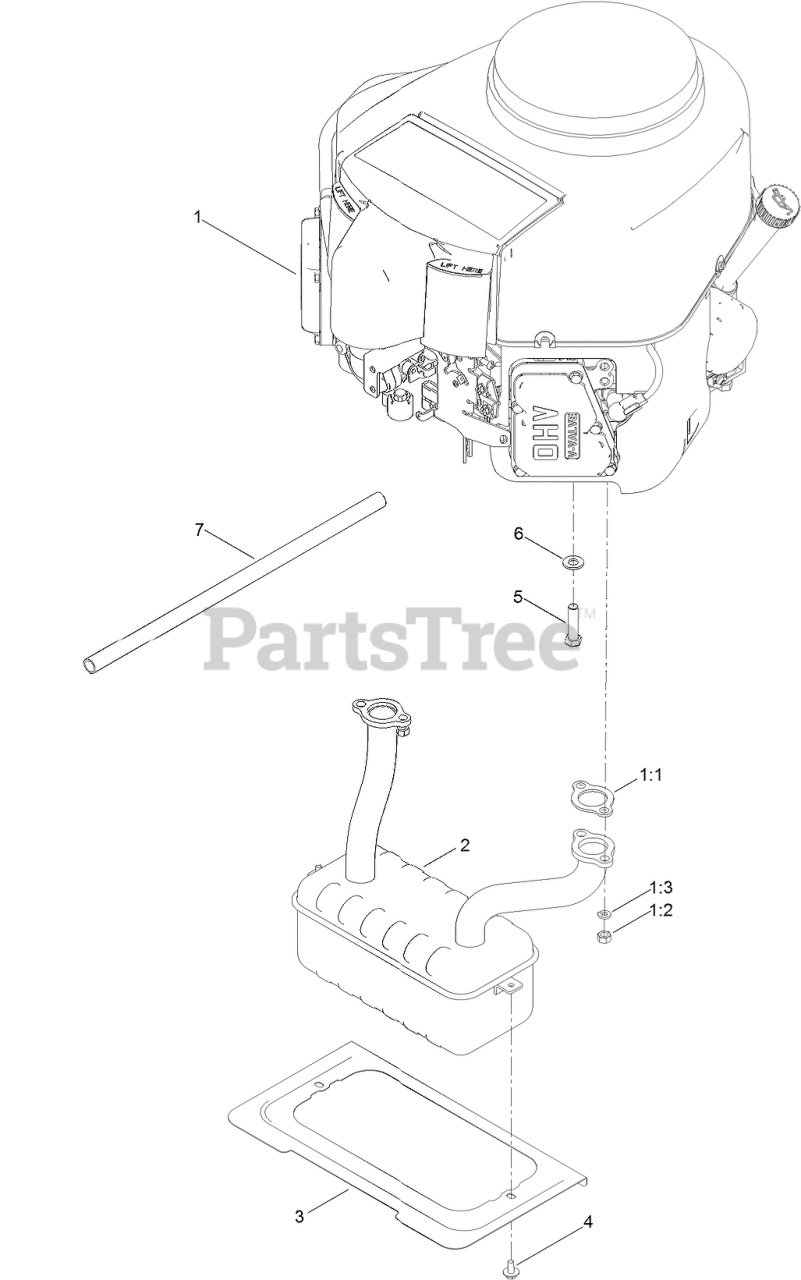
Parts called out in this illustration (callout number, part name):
1:1	GASKET-EXHAUST
1:3	WASHER-LOCK
2	MUFFLER
3	SHIELD-HEAT
4	SCREW-HHFTF
5	BOLT-HH
6	WASHER-FLAT
7	TUBE-DRAIN, OIL
